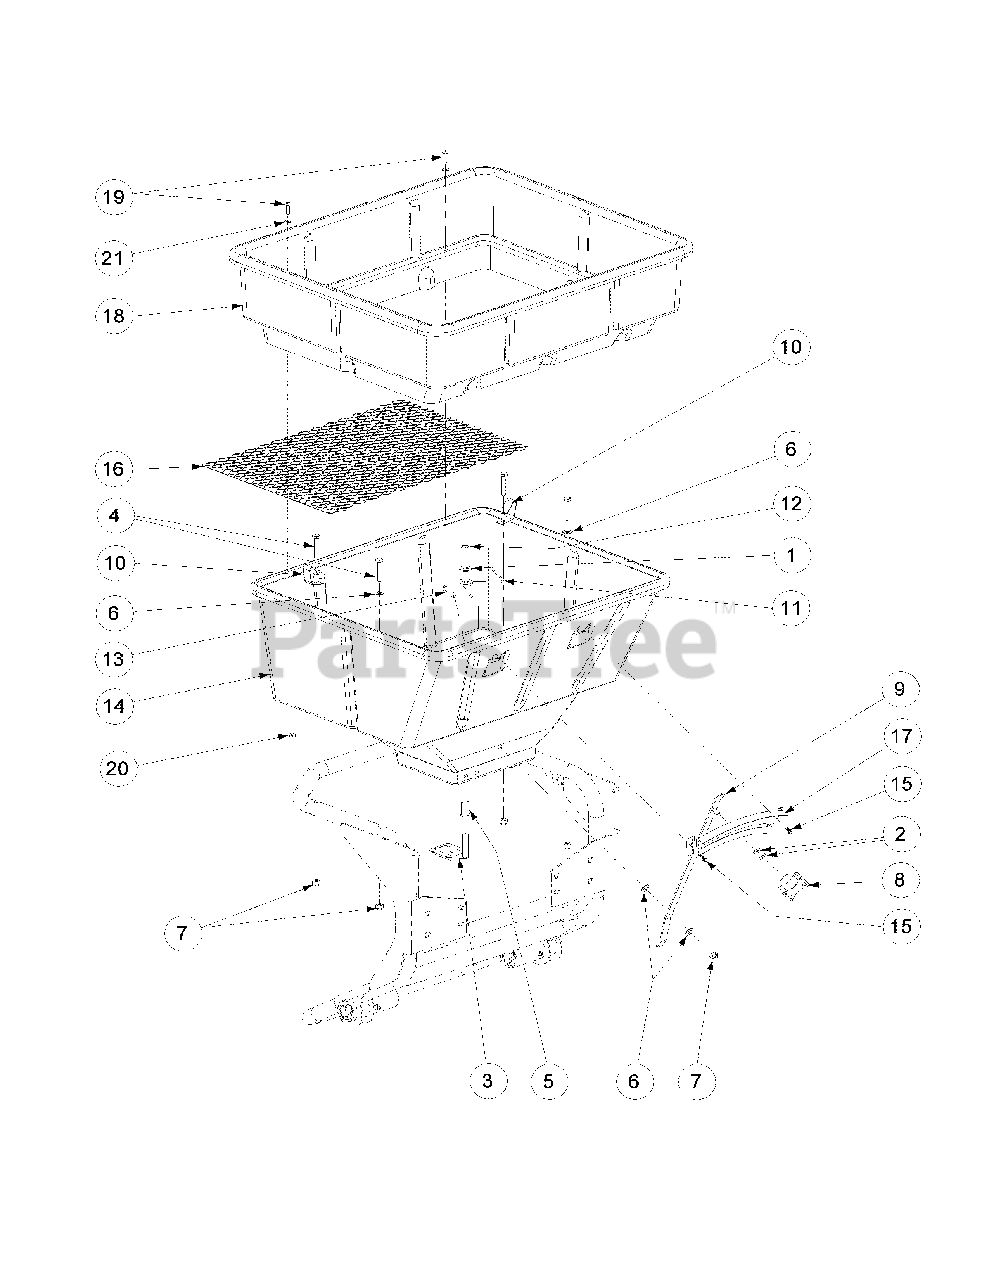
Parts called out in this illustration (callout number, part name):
1	Washer, 3/8
2	Washer, 1/4
3	Cam Agitator Assembly
4	Hex Cap Screw, 1/4-20 x 1.50
5	Agitator Bearing
6	Washer, 1/4, SS
7	Nut, 1/4-20, SS
8	Rate Control Knob
9	Rate Control Arm
10	Screen Clip, SS
11	Agitator Arm Assembly
12	Spring Retainer Clip
13	Machine Screw, 1/4-20 x 7/8
14	80# Hopper
15	Screw, #8 x 3/8, SS
16	Screen, SS
17	Rate Plate
18	Hopper Extension
19	Machine Screw, 10-24 x 3/4, SS
20	Nut, 10-24, SS
21	Washer, #8, SS
